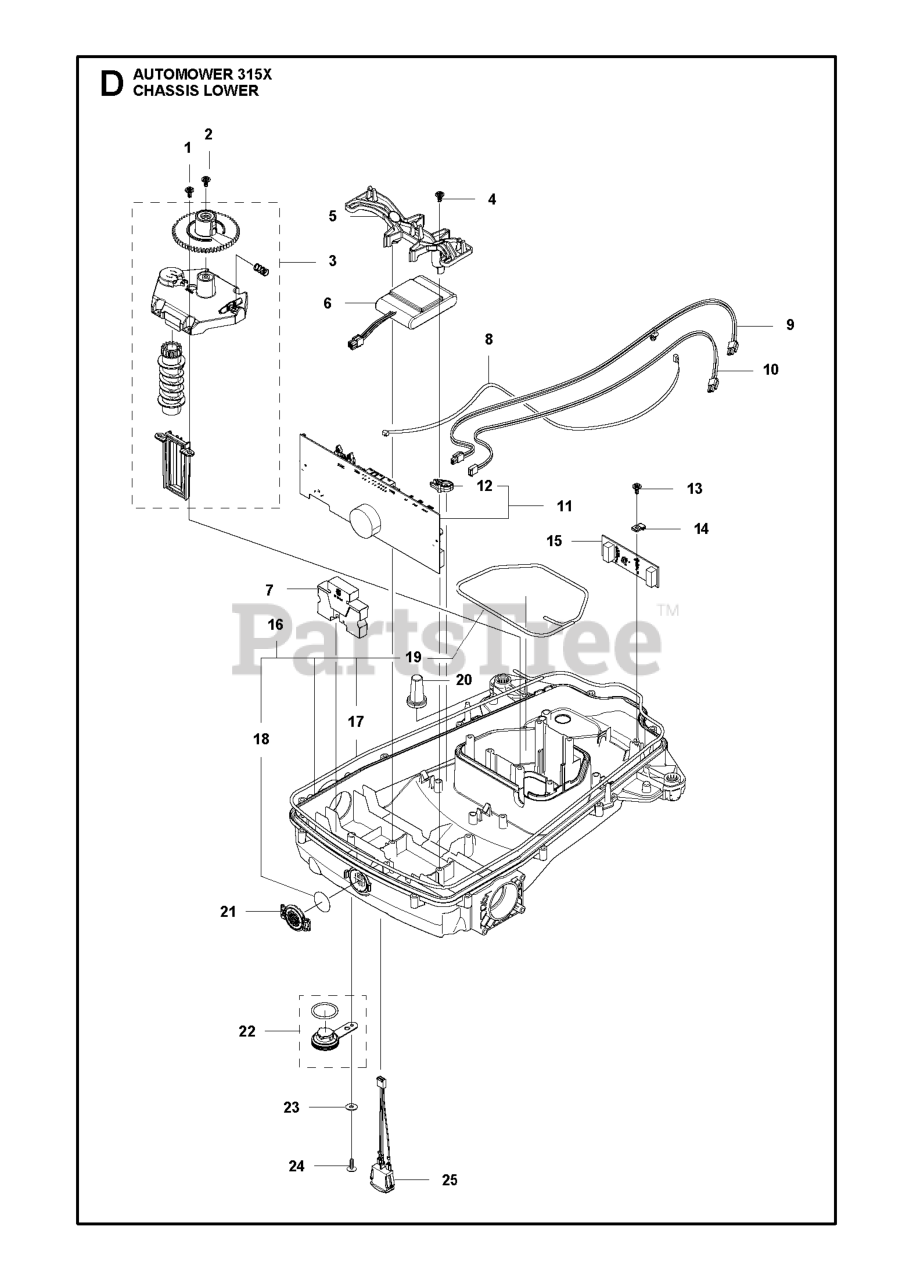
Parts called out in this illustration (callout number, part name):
1	SCREW ITXPANT
2	SCREW ITXPANT
3	COVER KIT
4	SCREW ITXPANT
5	HOLDER BATTERY AND WEIGHT
6	BATTERY LI-ION
7	WEIGHT 470G
8	LOOM LOOP SENSOR
9	LOOM CHARGING LINK
10	WIRING ASSY LED LIGHT EXTENSIO
11	PRINTED CIRCUIT ASSY MAIN BOAR
12	CLIP PCB
13	SCREW ITXPANT
14	CLAMP PCB
15	PRINTED CIRCUIT ASSY LOOP SENS
16	Chassis
17	SEALING STRIP P 15 CHASSI LOW
18	KIT AIR FILTER KIT 305 - 10 PC
19	SEALING STRIP P15 UPPER
20	COLUMN FRONT
21	COVER AIR FILTER
22	PLUG KIT
23	WASHER
24	SCREW ITXPANT
25	LOOM ON/ OFF
